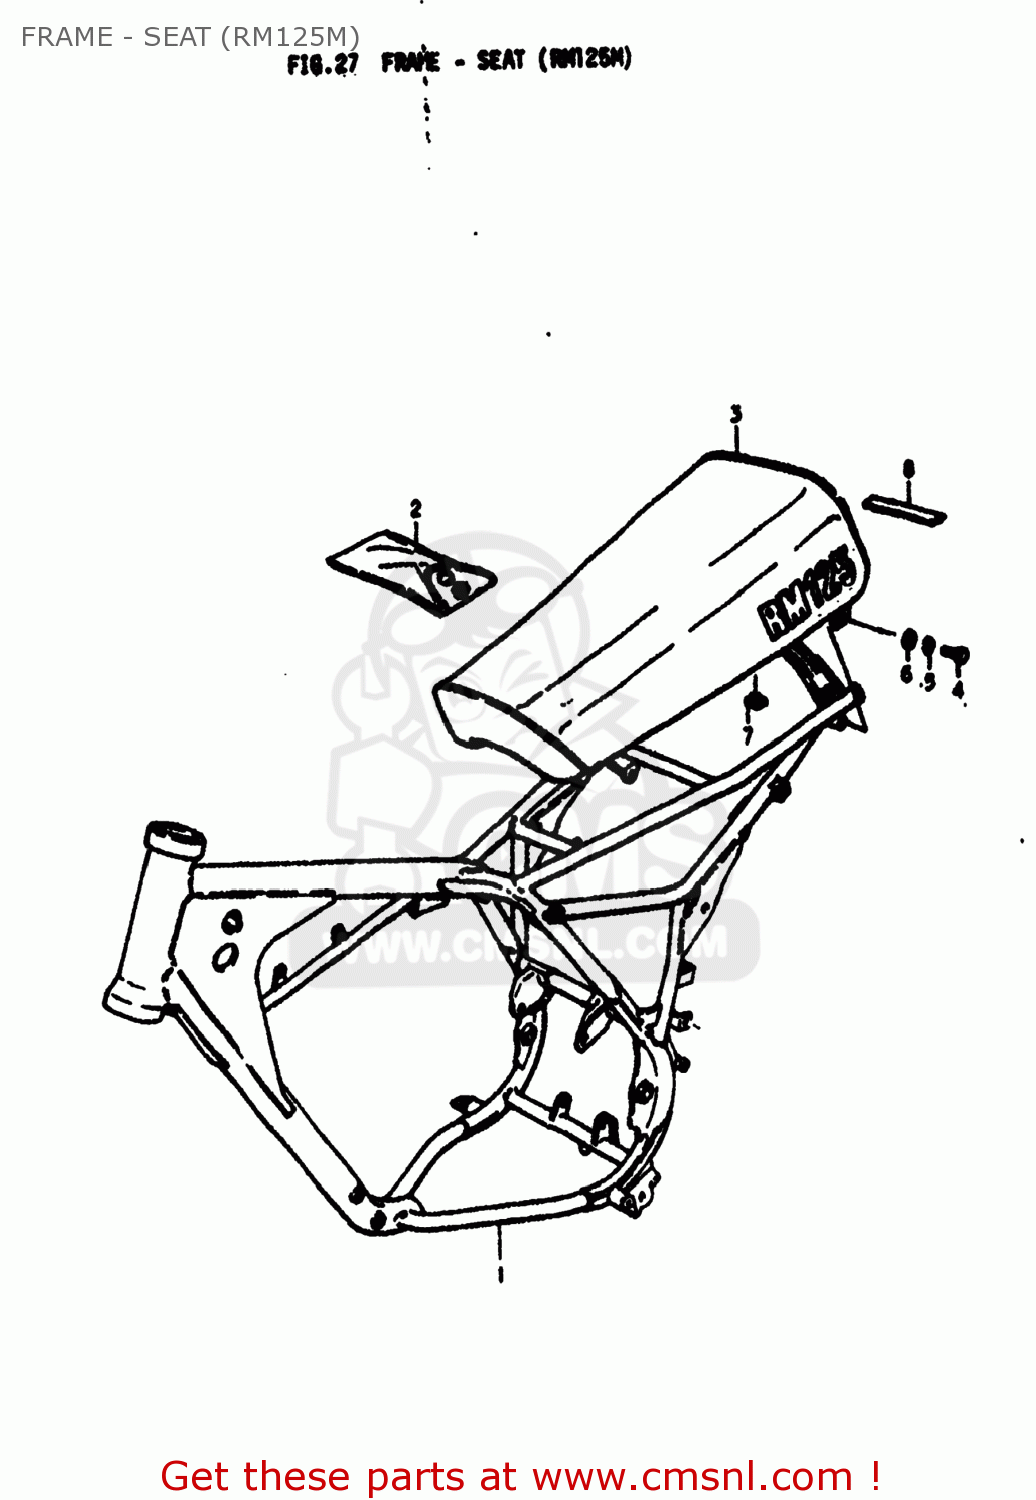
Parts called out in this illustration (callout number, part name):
1	FRAME
3	SEAT ASSEMBLY
4	BOLT
5	LOCK WASHER
6	WASHER
7	CUSHION
8	CUSHION,FRAME
